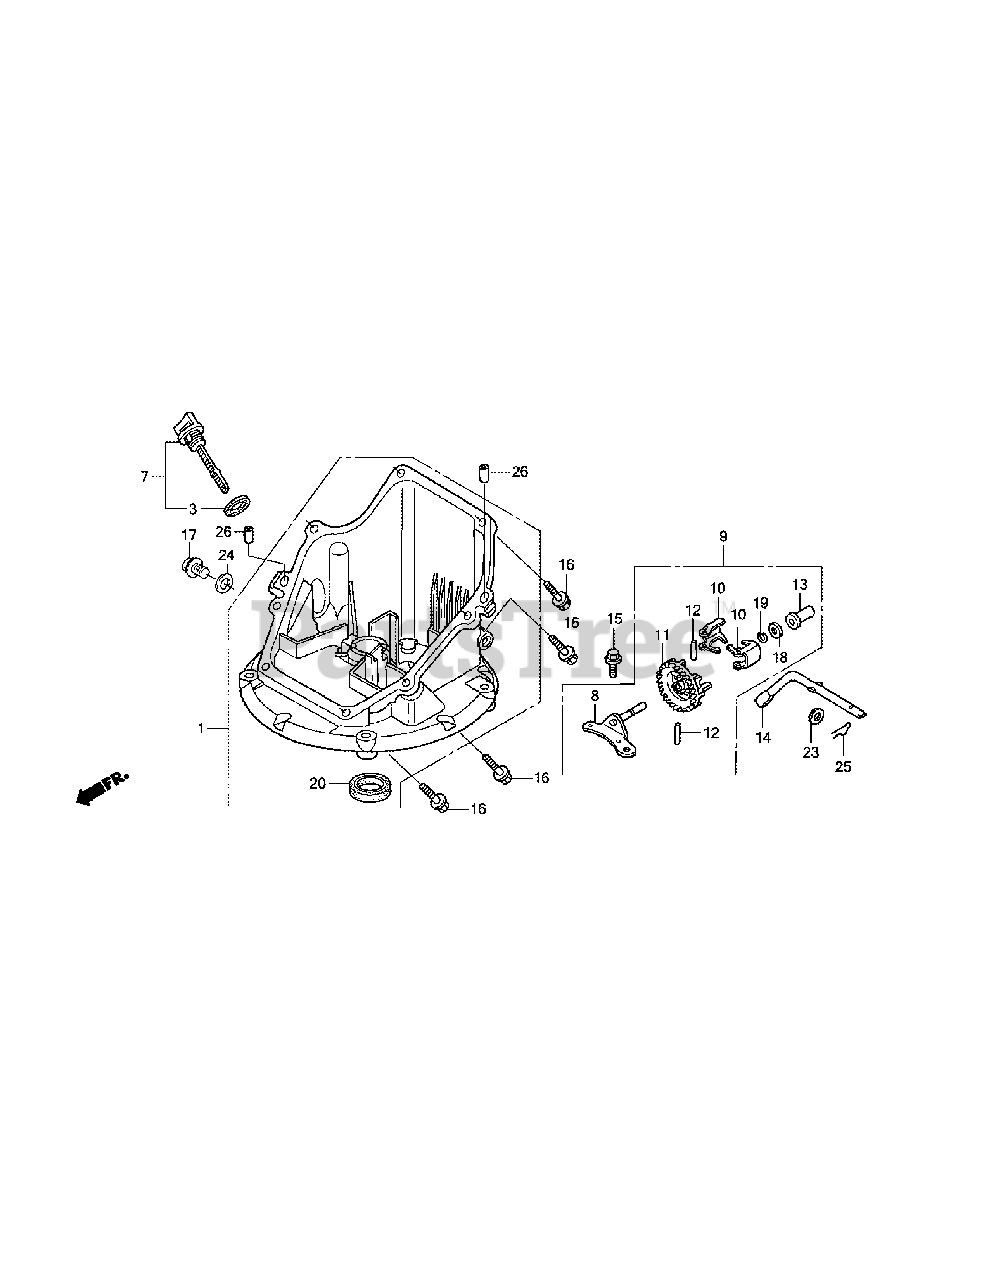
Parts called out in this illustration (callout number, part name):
1	Oil Pan Assembly
3	Oil Filler Cap Gasket
7	Oil Level Gauge Assembly
8	Governor Holder Shaft
9	Governor Assembly
10	Governor Weight
11	Governor Weight Holder
12	Governor Weight Pin
13	Governor Slider
14	Governor Arm Shaft (to 1642935)
14	Governor Arm Shaft (from 1642936)
15	Flange Bolt, 6 x 14
16	Flange Bolt, 6 x 25
17	Drain Plug Bolt
18	Thrust Washer, 6mm
19	Governor Holder Clip
20	Oil Seal, 28 x 41.25 x 6
23	Plain Washer, 6mm
24	Drain Plug Washer, 12mm
25	Lock Pin, 8mm
26	DowelPin, 8x20
